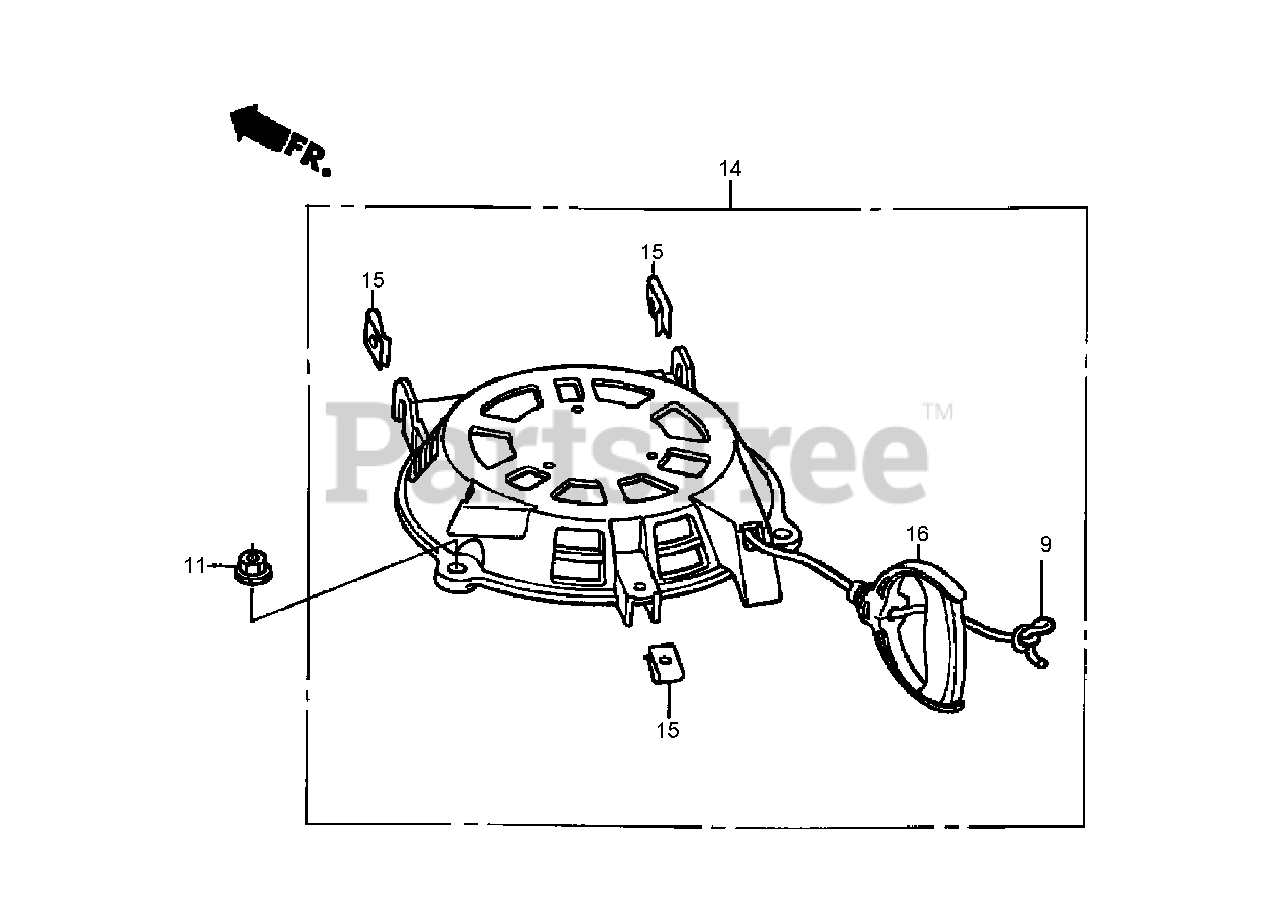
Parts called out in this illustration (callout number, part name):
9	ROPE-STARTER, RECOIL
11	NUT-FLANGE (6MM)
14	RECOIL STARTER ASM
15	NUT-COWL
16	KNOB-STARTER, RECOIL
